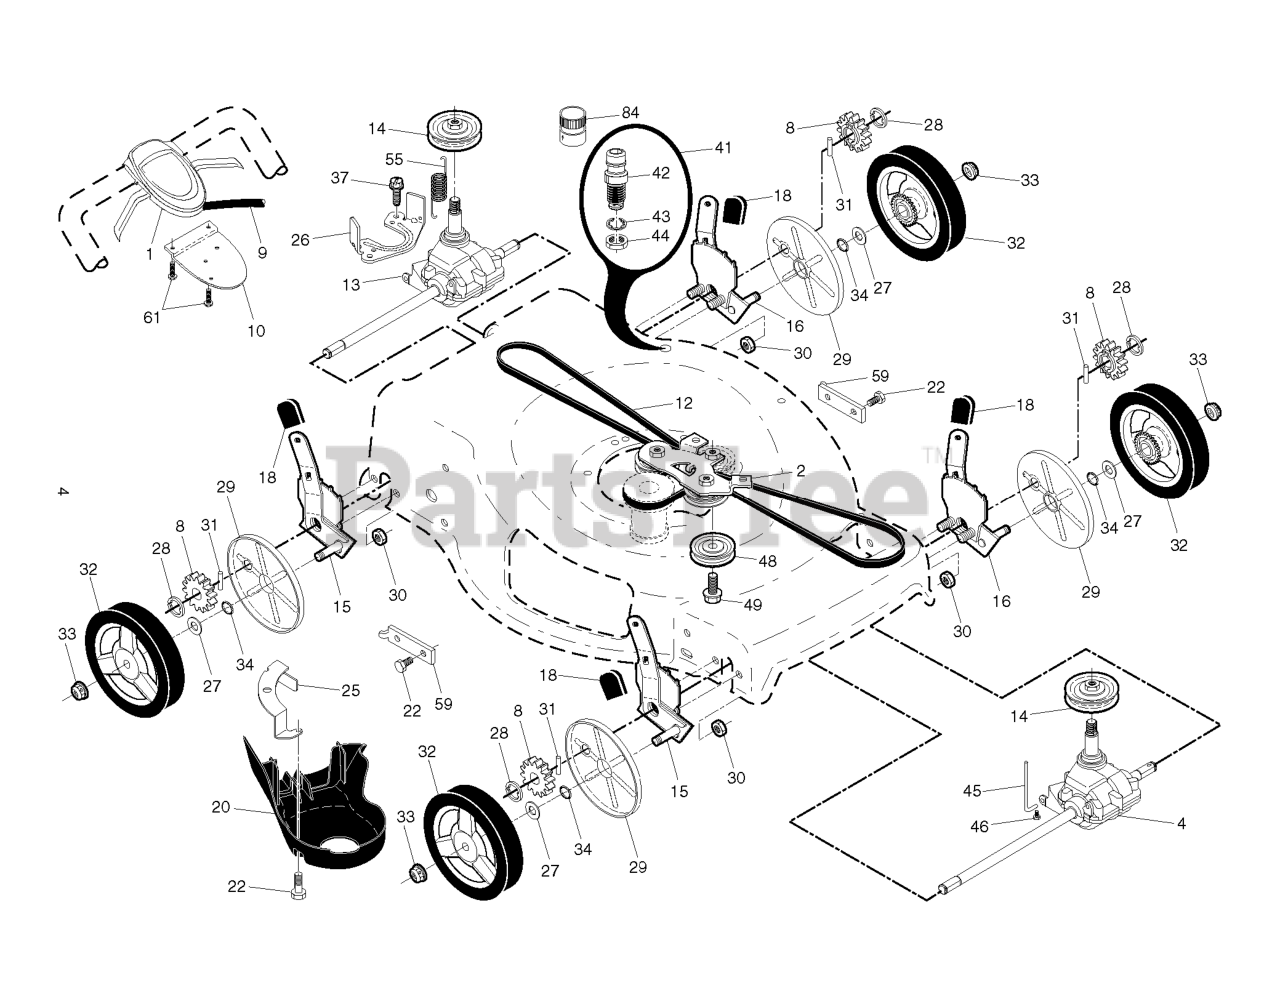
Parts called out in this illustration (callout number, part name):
1	CONTROL.22+AWD.AW2.BS.GRY/BLK
2	BRACKET.ASM.AWD.BZP
4	RP TRANSMISSION.22+.AWD.FRONT
8	PINIION.14.TOOTH.RGD
9	CABLE.DRIVE.RWD.WALK.
10	BRACKET.DRIVE.CONTR.GEN2.BLACK
12	BELT.DRIVE.AWD.PLUS.13
13	TRANSMISSION.22+AWD.WALK.MOWER
15	RP_ADJUSTER.ASM.AWD.RT.ZINC
16	RP_ADJUSTER.ASM.AWD.LT.ZINC
18	SELECTOR KNOB
20	COVER.REAR.DRIVE.22+2013
22	BOLT.5/16HEX.WHS.HD
25	BRACKET.DRIVE.COVER.RGD.BZP
26	BRACKET.TRAN.BELTKEEPER.22+RGD
27	WASHER FLUT
28	E-RING 7/16 RE
29	COVER.DUST.WHEEL.INNER.WALK
30	NUT.FLANGE.1-4-20-SERR
31	PAWL, DRIVE
32	WHEEL.8".AWD.3SP.EXT.DR.GREY
33	NUT.HEX.FLANGE.3/8-16.LO(3 2)
34	O-RING..070X.487.NEOPRENE
41	KIT.WASH-OUT.PORT.ZINC.WALK
42	WASHOUT.PORT.ZINC.RGD.22+
43	WASHER.LOCK.INTERNAL.TOOTH
44	LOCKNUT.HEX.WITH.O-RING
45	BRACKET.AWD.FRONT.BELT.KEEPER
46	SCREW.HI-LO.5/16 X.75
48	RP PULLEY.IDLER.ASM
55	SPRING.RETURN.AUTO.
59	BRACKET.SUPPORT.22+RWGD.BZP
61	SCREW, PHILLIPS HEAD 10 X 5/8
84	COUPLING.QUICK CONNECT
